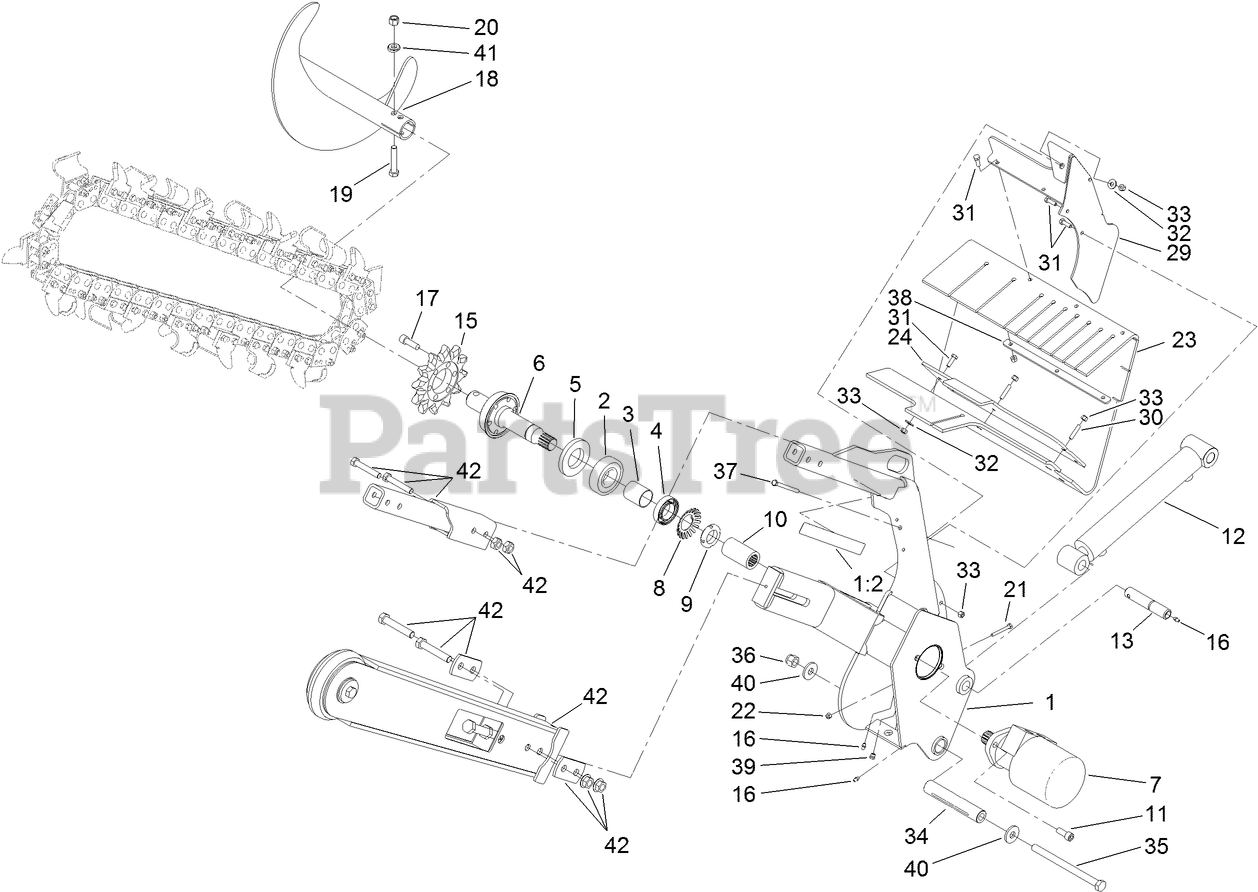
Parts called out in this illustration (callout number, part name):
1	TRENCHER HEAD ASM
1:2	DECAL-DANGER
2	BEARING-BALL
3	SPACER
4	BEARING-BALL
5	SEAL-GREASE
6	SHAFT-TRENCHER
7	MOTOR-HYD
8	LOCKWASHER-BEARING
9	LOCKNUT-BEARING
10	SPLINE-COLLAR
11	SCREW-HSH
12	HYD CYLINDER ASM
13	PIN-PIVOT
15	SPROCKET-TRENCHER
16	FITTING-GREASE
17	SCREW-HSH
18	AUGER-TRENCHER
19	SCREW-HH
20	NUT-LOCK, NI
21	SCREW-HH
22	NUT-LOCK, NI
23	SHIELD-DIRT
24	BAR-CLAMP
29	BRACKET-SHIELD
30	SCREW-HSH
31	SCREW-HH
32	WASHER-FLAT
33	NUT-LOCK, NI
34	SPACER-PIVOT
35	BOLT-HH
36	NUT-LOCK, NI
37	SCREW-HH
38	PLATE-STRAP, SHIELD
39	FITTING-LUBE
40	WASHER-HARDENED
41	WASHER-SADDLE
42	BOOM ASM
